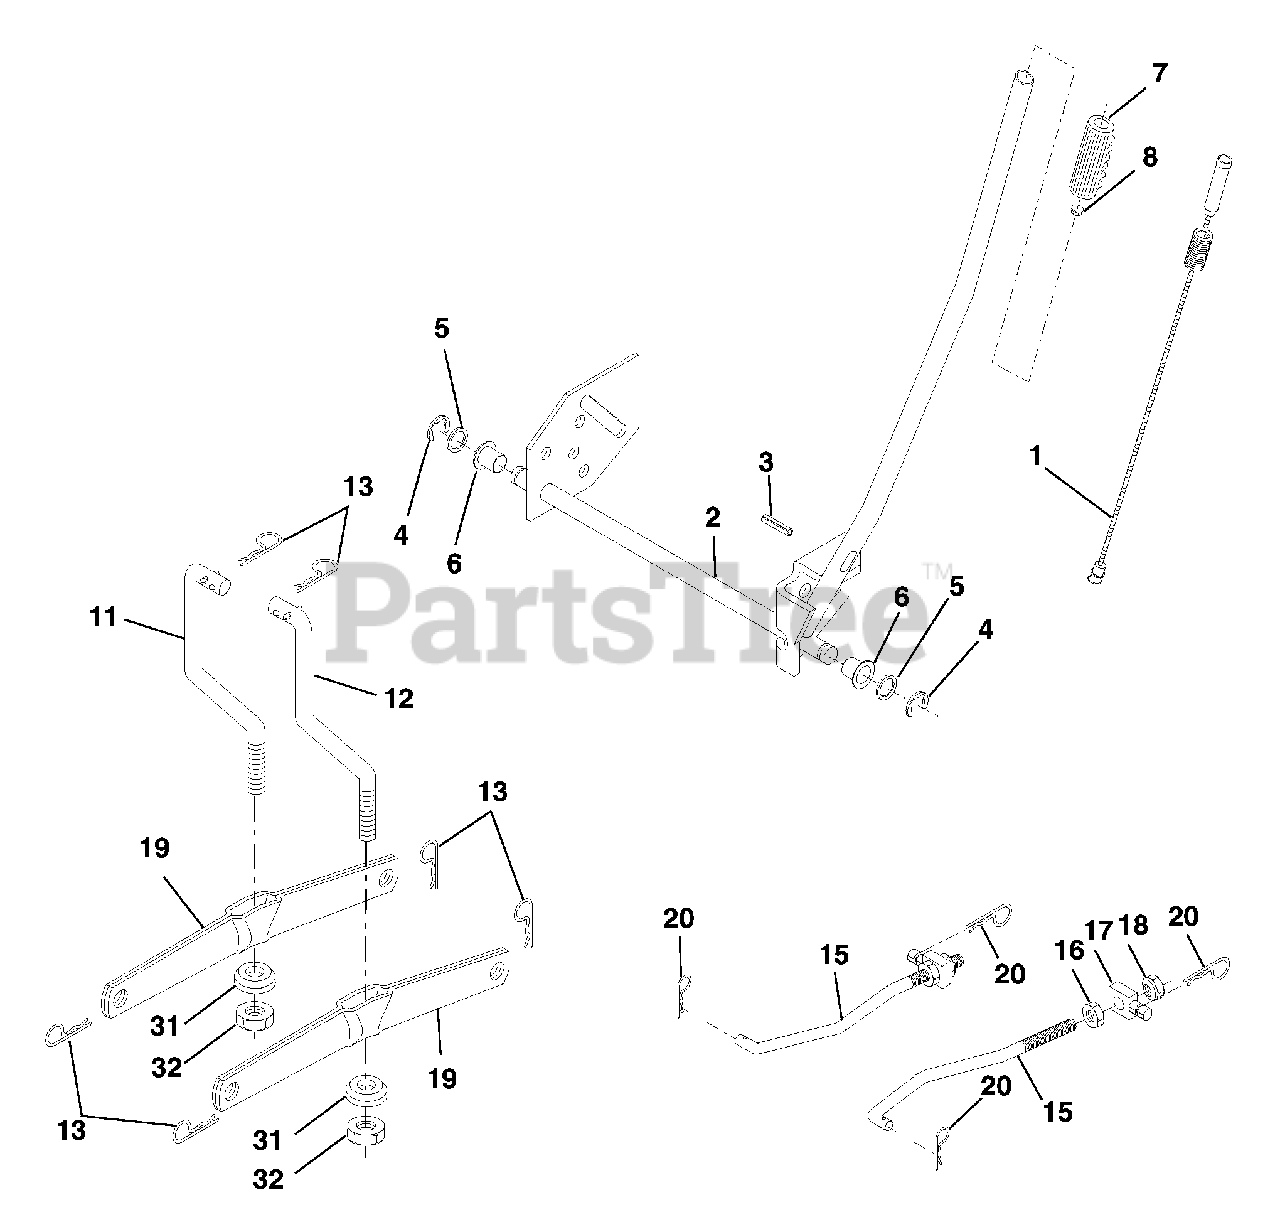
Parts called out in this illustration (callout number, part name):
1	Wire Asm Inner/Sprg W/plunger
2	Shaft Asm Lift RH w/Inf
3	Pin Groove 5/16 Dia x 1.875
4	E Ring #5133-62
5	Washer 21/32 x 1 x 21 Ga.
6	Bearing Nylon Blk 629 Id
7	Grip Handle
8	Button Plunger
11	Link Lift LH Fixed Length
12	Link Lift RH Fixed Length
13	Retainer Spring
15	Link Front
16	Nut Jam Hex 1/2-13 unc
17	Trunnion
18	Nut Lock W/Wsh 1/2-13 unc
19	Arm Suspension Rear
20	Retainer Spring
31	Bearing Pvt Lift
32	Nut Crownlock 3/8 - 24
